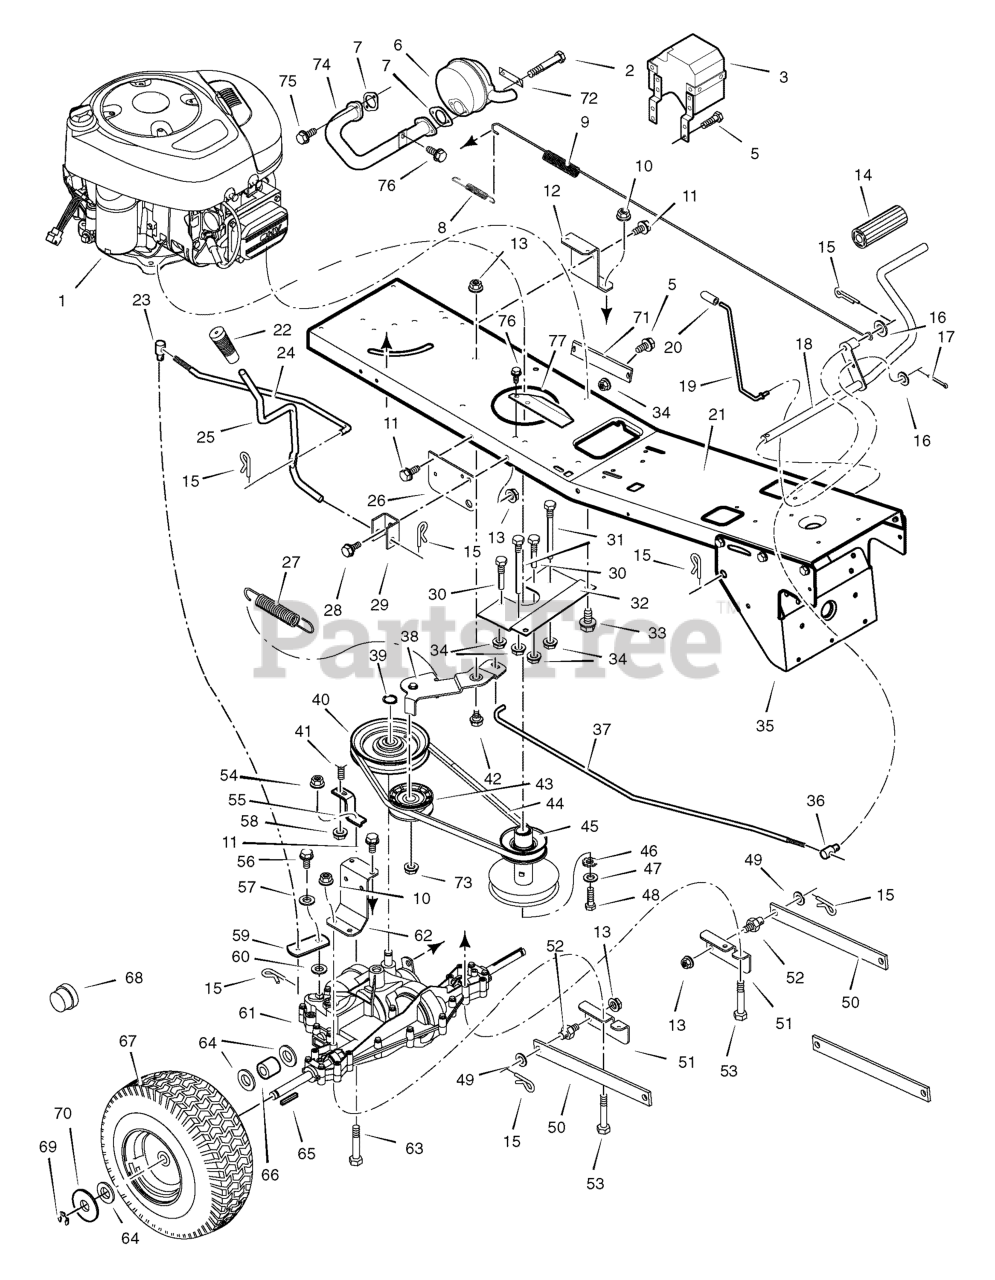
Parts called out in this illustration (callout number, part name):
1	Engine, Briggs & Stratton *
2	BOLT, Hex
3	SHIELD ASSEMBLY, Heat
7	GASKET, Exhaust
8	SPRING, Extension
9	SPRING, Extension
10	NUT
12	BRACKET, Left Transaxle
13	NUT, Flange
14	COVER, Pedal
15	PIN, Cotter
16	WASHER
17	PIN, Cotter
18	PEDAL ASSEMBLY
19	ROD, Parking Brake
20	GRIP, Parking Brake Rod
22	GRIP, Shift Lever
23	NUT, Adjusting
24	LINK, Shift
25	LEVER, Shift
26	BRACKET, Lift Pivot
27	SPRING, Extension
28	BOLT, Shoulder
29	BRACKET, Pivot
30	GUIDE, Belt Short
31	GUIDE, Belt Long
32	PLATE, Belt Guide
33	BOLT
34	NUT, Flange
35	BRACKET, Support
36	NUT, Adjusting
37	ROD, Clutch
38	CLUTCH ARM ASSEMBLY
39	RING, Retainer
40	PULLEY, Drive
41	BOLT, Carriage
42	BOLT, Shoulder
43	PULLEY, Idler
44	BELT, Motion Drive
45	PULLEY, Split Stack
46	WASHER, Star
48	BOLT, Hex
51	BRACKET, Rear Hanger
52	PIN, Threaded Shoulder
53	BOLT, Hex
54	NUT
55	BRACKET, Torque Reactor
57	WASHER, Shift Yoke
58	NUT
59	YOKE, Shift
61	Transaxle, Peerless **
62	BRACKET, Right Transaxle
63	BOLT, Hex
65	KEY, Square
66	SPACER, Rear Wheel
67	WHEEL, Rear, 15"
68	CAP, Hub
71	PLATE, Reinforcement
72	SCREW, Lock
73	NUT
74	TUBE, Exhaust
77	SHIELD, Heat
